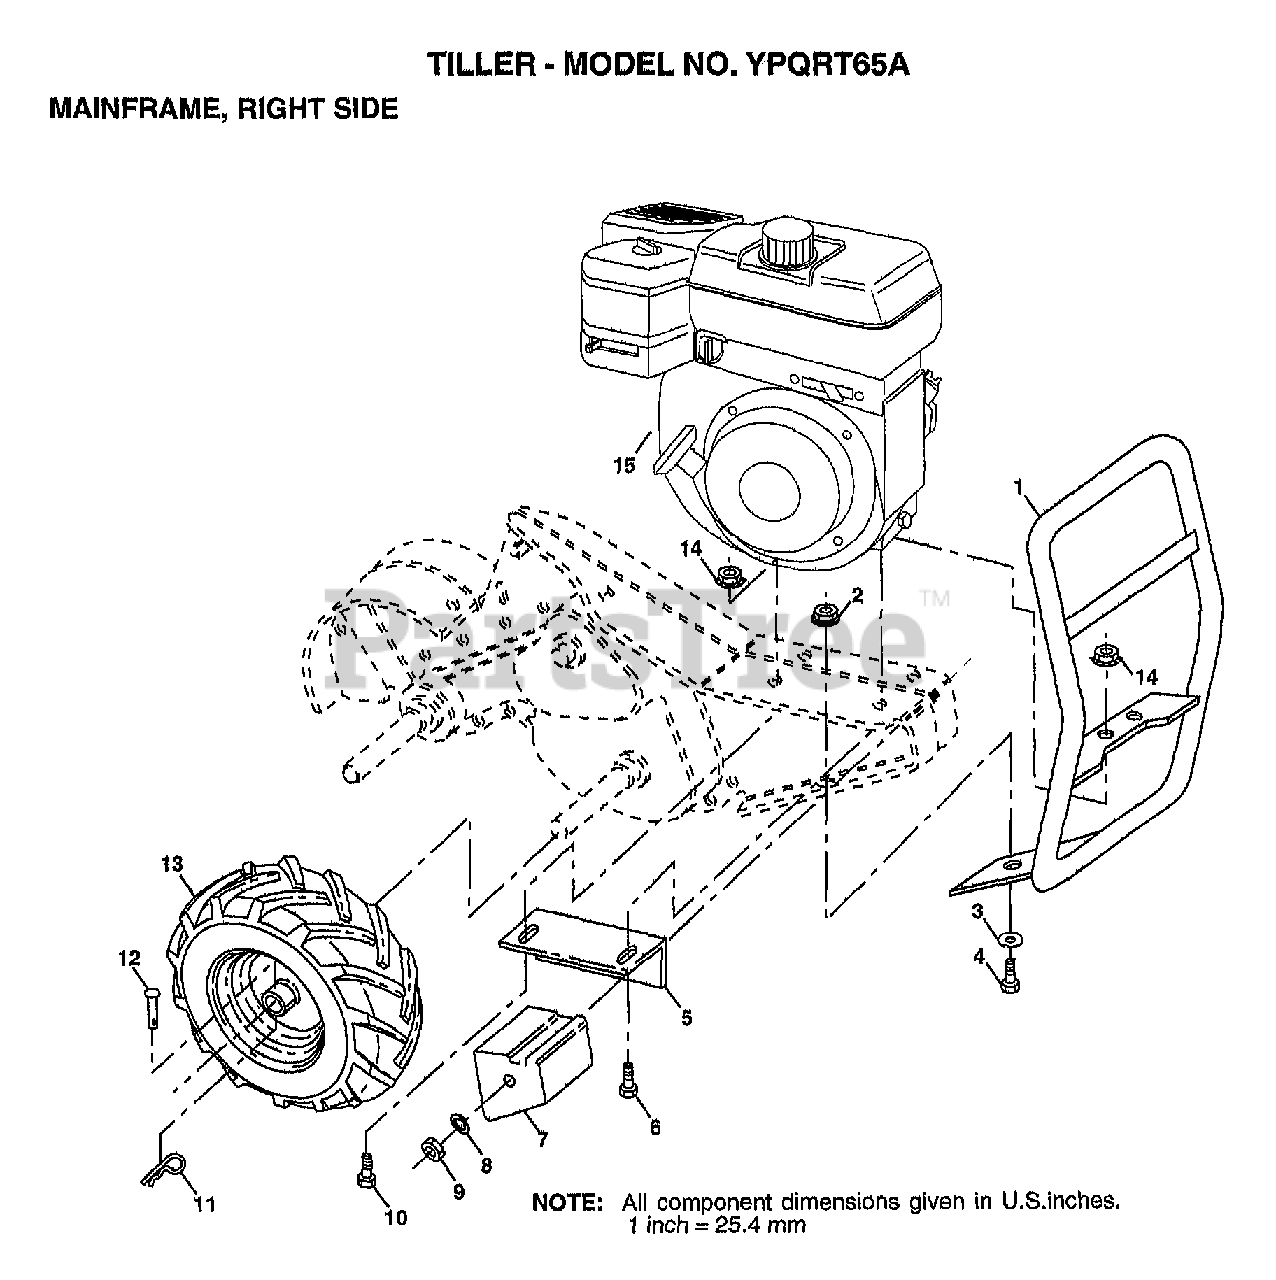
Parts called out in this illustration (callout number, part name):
1	BUMPER ASM.TILLER
2	LOCKNUT TI
3	WASHER
4	BOLT
5	BRACKET RH CRT
6	BOLT
7	COUNTERWEIGHT CRT
8	LOCKWASHER
9	NUT.HEX.3/8-16UNC
10	BOLT.HEX.5/16-1.5
11	RETAINER M
12	RIVET.DRILL.1.75
13	TIRE TI
13	RIM
